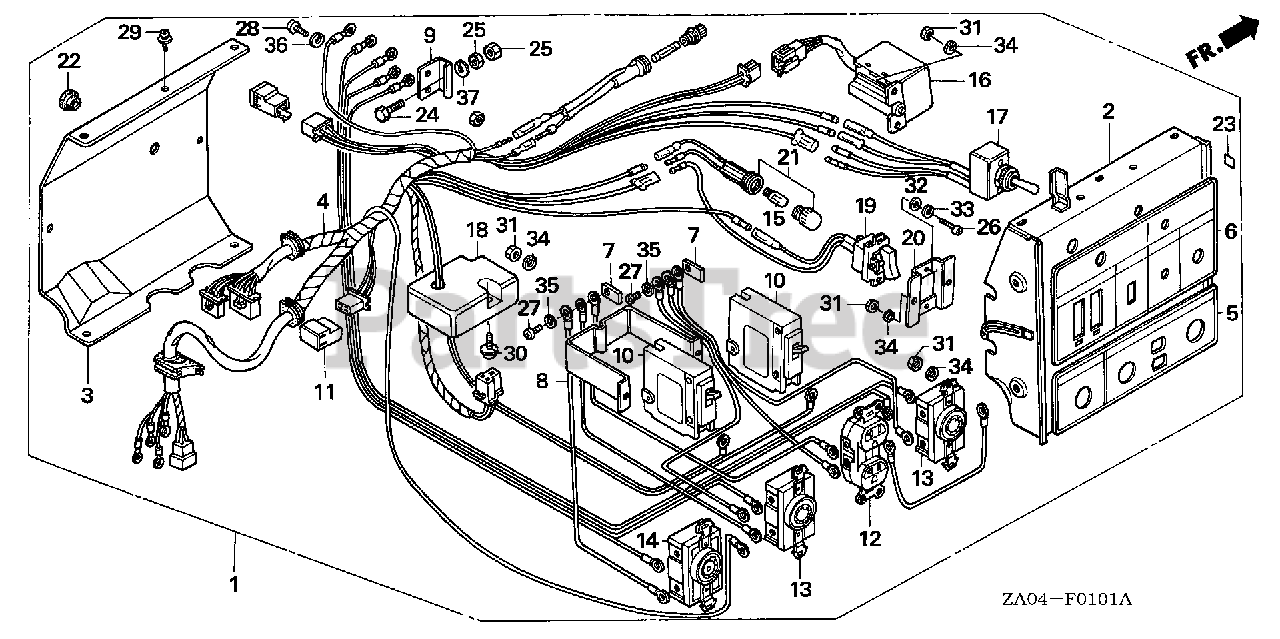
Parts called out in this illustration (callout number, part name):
1	BOX ASSY., CONTROL *NH105* (MAT BLACK)
2	PANEL, FR.
4	WIRE HARNESS (NOT AVAILABLE)
5	MARK, RECEPTACLE PANEL
6	MARK, SWITCH PANEL
7	TERMINAL, BREAKER
8	SUPPORT, BREAKER
9	PLATE, GROUND
10	BREAKER, CIRCUIT (21A) (NOT AVAILABLE)
11	STACK ASSY., DIODE (2.7A)
12	RECEPTACLE ASSY. (20A/125V) (MATSUSHITA)
12	RECEPTACLE (20A/125V)
13	RECEPTACLE (20A/125V) (NOT AVAILABLE)
14	RECEPTACLE (20A-125/250V) (MATSUSHITA) (NOT AVAILABLE)
15	BULB, DASH (24V-2W)
16	RELAY, ALERT
17	SWITCH ASSY., ENGINE (NOT AVAILABLE)
18	CONTROL UNIT, IDLE
19	SWITCH ASSY., IDLE CONTROL
20	STAY, SWITCH
21	SOCKET ASSY., PILOT LAMP
22	GROMMET, TOP COVER
23	MARK, GROUND
24	BOLT, HEX. (8MM)
25	NUT, HEX. (8MM) (NOT AVAILABLE)
26	SCREW, PAN (3X8)
27	SCREW, PAN (5X10)
28	SCREW, PAN (6X12)
29	SCREW-WASHER (4X8)
30	SCREW-WASHER (5X10)
31	NUT, HEX. (4MM)
32	WASHER, PLAIN (3MM)
33	WASHER, SPRING (3MM)
34	WASHER, SPRING (4MM)
35	WASHER, SPRING (5MM)
36	WASHER, SPRING (6MM)
37	WASHER, SPRING (8MM)
